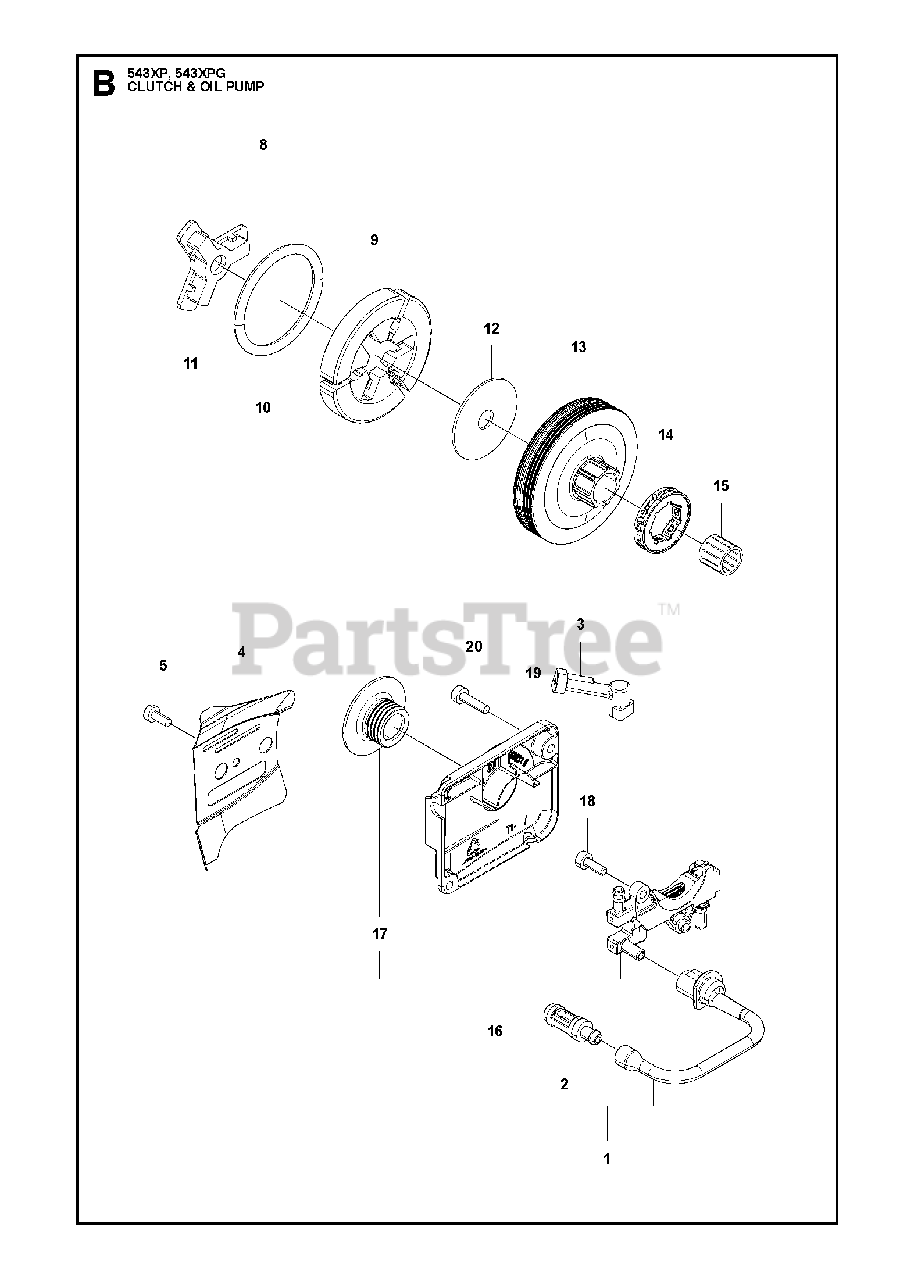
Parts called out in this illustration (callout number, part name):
1	OILPIPE COMP 848C806732
2	RP_FILTER
4	BAR MOUNT PLATE
5	SCREW
8	CLUTCH ASSY (RPLS 267051200)
9	SHOE
10	SPRING
11	BOSS 848C8051F1
13	DRUM
16	OIL PUMP SET (RPLS 848C806711)
17	WORM
18	BOLT
19	PUMP COVER
20	BOLT M4 X 12 T27
